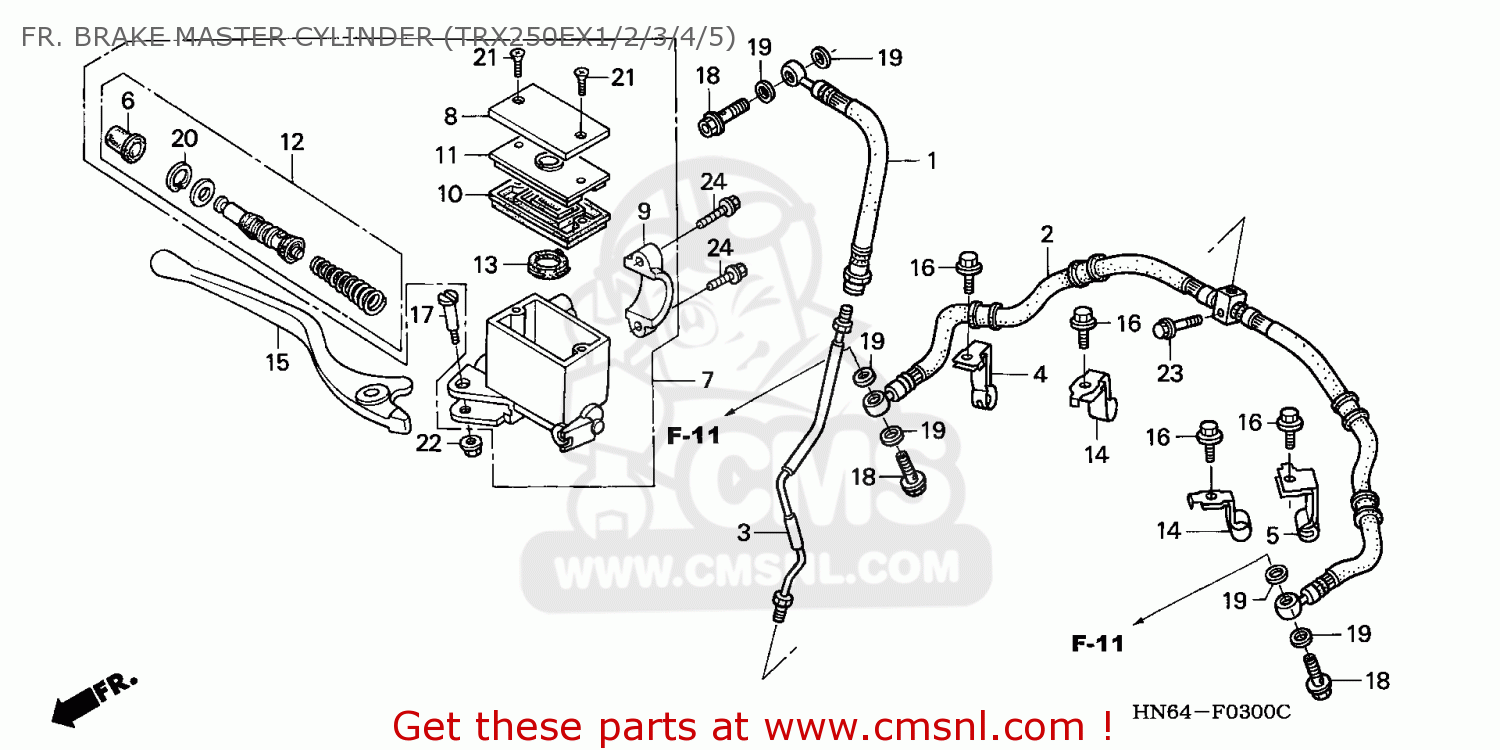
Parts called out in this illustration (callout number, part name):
1	HOSE COMP A,FR BR
2	HOSE COMP B,FR BR
3	PIPE COMP,FR BRK
4	CLAMP A,FR BRK HO
5	CLAMP A,FR BRK HO
6	BOOT COMP.
7	SUB ASSY,FRONT M/
8	CAP,MASTER CYLIND
9	HOLDER,MASTER CYL
10	DIAPHRAGM
11	PLATE,DIAPHRAGM
12	CYLINDER SET,MAS
13	SEPARATOR COMP.
14	CLAMP B,FR BRK HO
15	LEVER,R STRG HNDL
16	BOLT,FLANGE,6X10
17	BOLT,HANDLE LEVER
18	OIL BOLT,10X22
20	CIRCLIP
21	SCREW,FLAT 4X12
23	BOLT,FLANGE,6X16
24	BOLT,FLANGE,6X22
